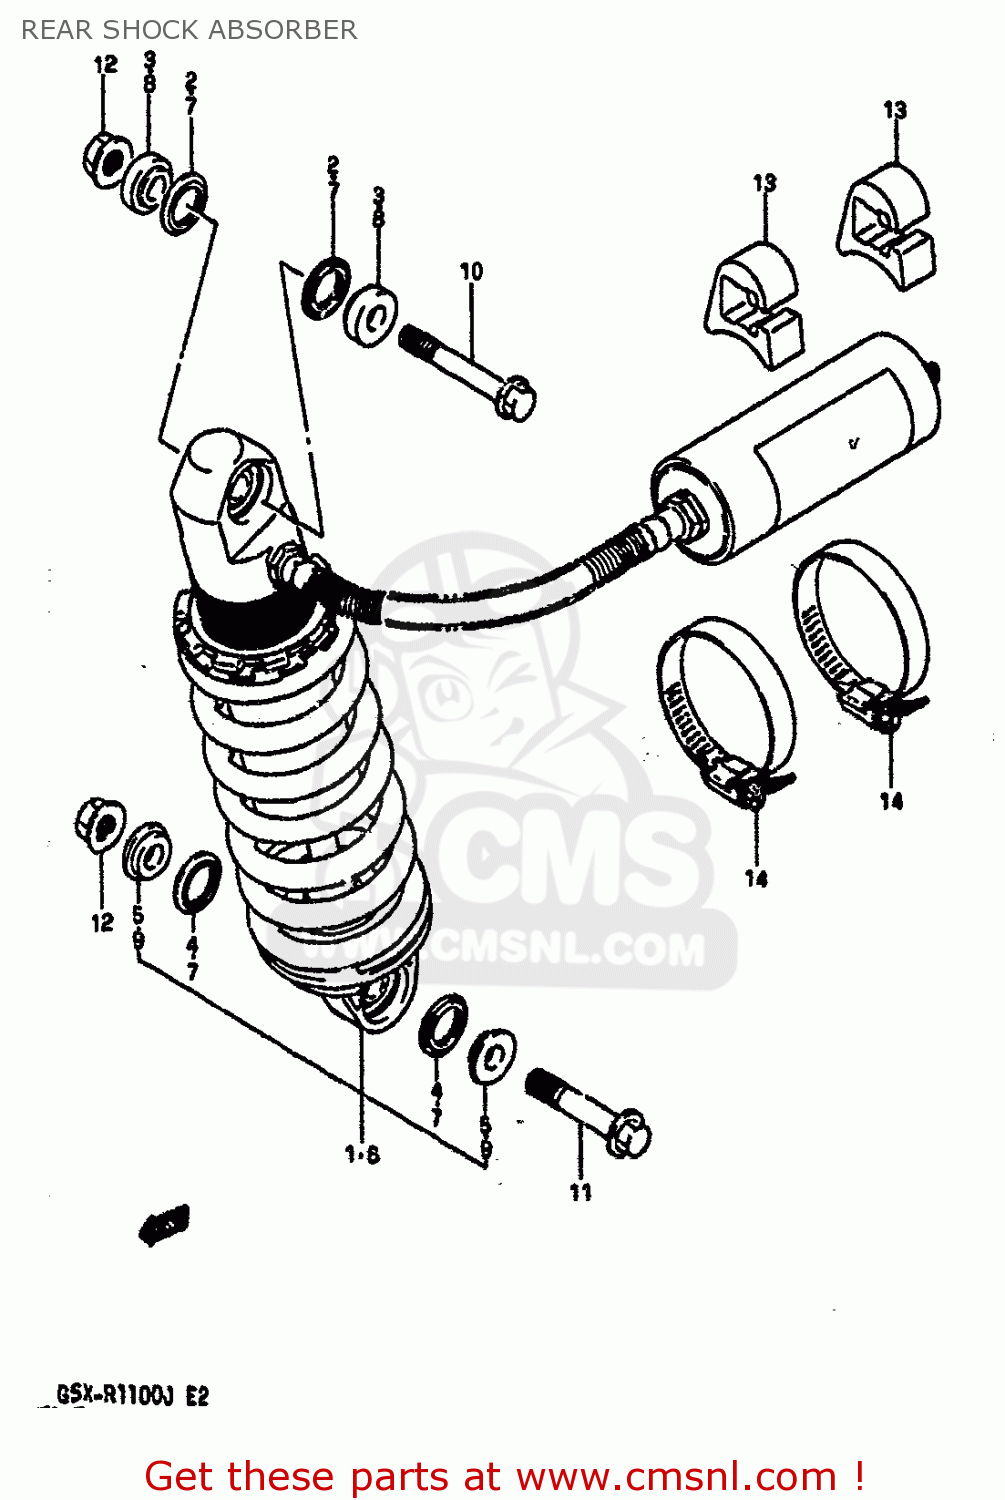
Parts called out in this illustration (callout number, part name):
1	ABSORBER ASSY,REAR SHOCK
2	SEAL,DUST RR SHOCK ABSORBER
3	COLLAR
4	O-RING,FORK INNER TUBE
5	SPACER,REAR SHOCK,UPPER
6	ABSORBER ASSY,REAR SHOCK
7	SEAL DUST
8	COLLAR
9	COLLAR
10	BOLT
11	BOLT(10X48)
12	NUT
13	CUSHION,RESERVOIR TANK
14	CLAMP
